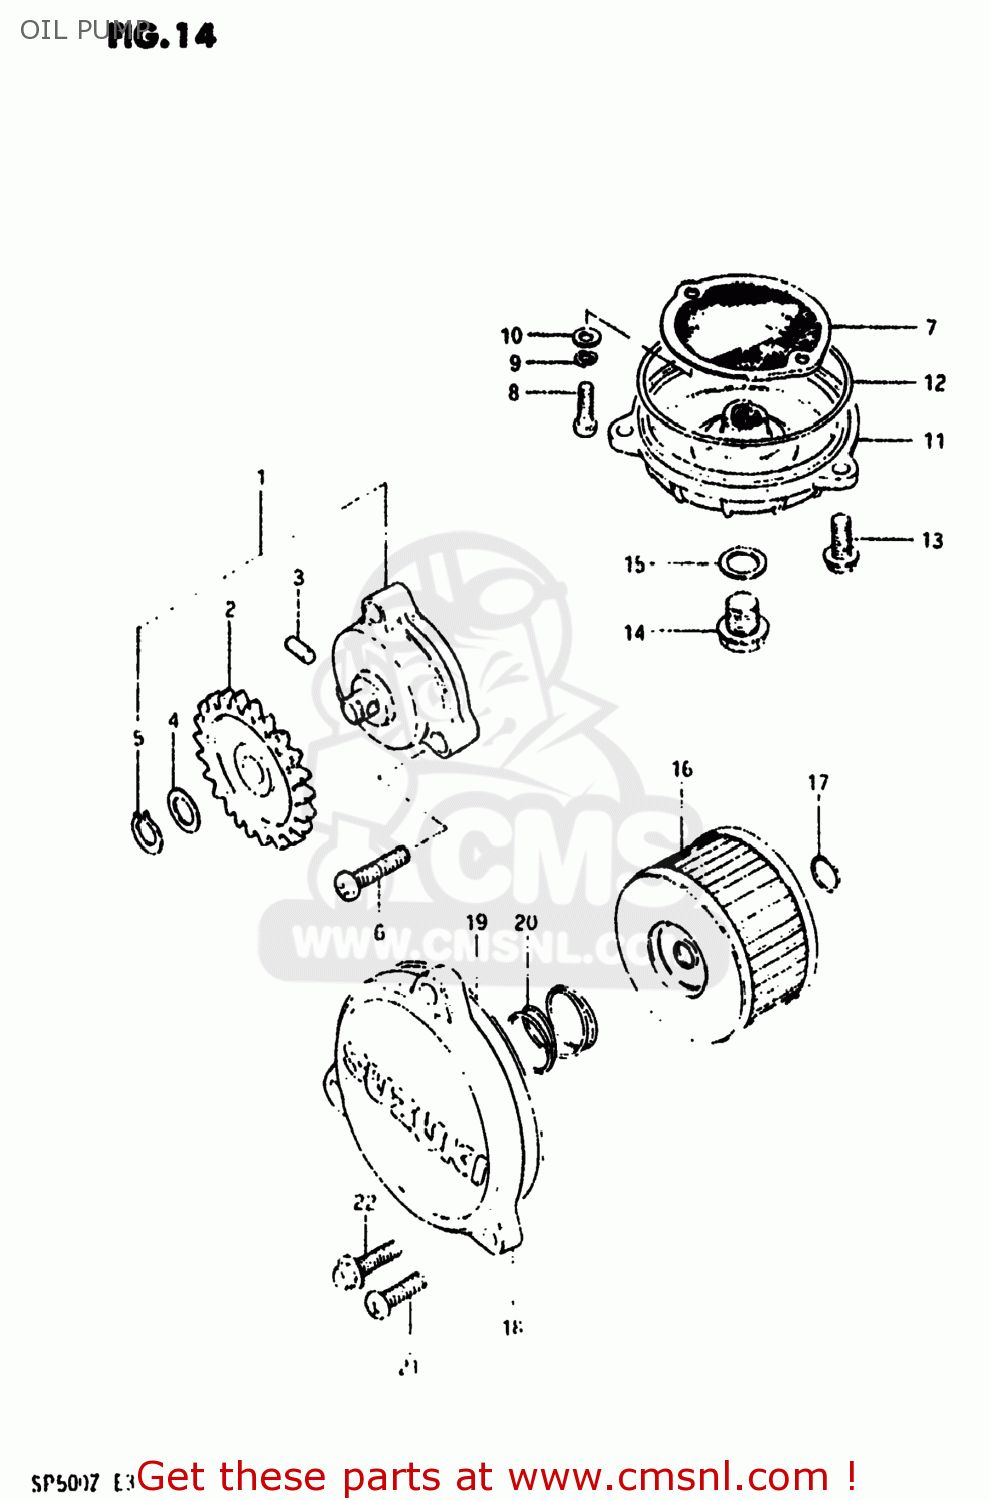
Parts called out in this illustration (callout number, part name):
1	PUMP ASSY,ENGINE OIL
2	GEAR,OIL PUMP DRIVEN
3	PIN(4X15.8)
4	SHIM
5	CIRCLIP
6	SCREW
7	STRAINER,ENGINE OIL
8	SCREW
9	LOCK WASHER
10	WASHER
11	CAP,OIL STRAINER
12	O RING(D:2.4,ID:85)
13	BOLT,REAR
14	PLUG (14X12)
15	GASKET(14X19.2X2) (NAS)
16	FILTER,ENGINE OIL
17	O RING(D:2.4,ID:15.8)
18	CAP,ENGINE OIL FILTER
19	O RING(D:2.4,ID:73)
20	SPRING
21	SCREW
22	BOLT (6X20)
